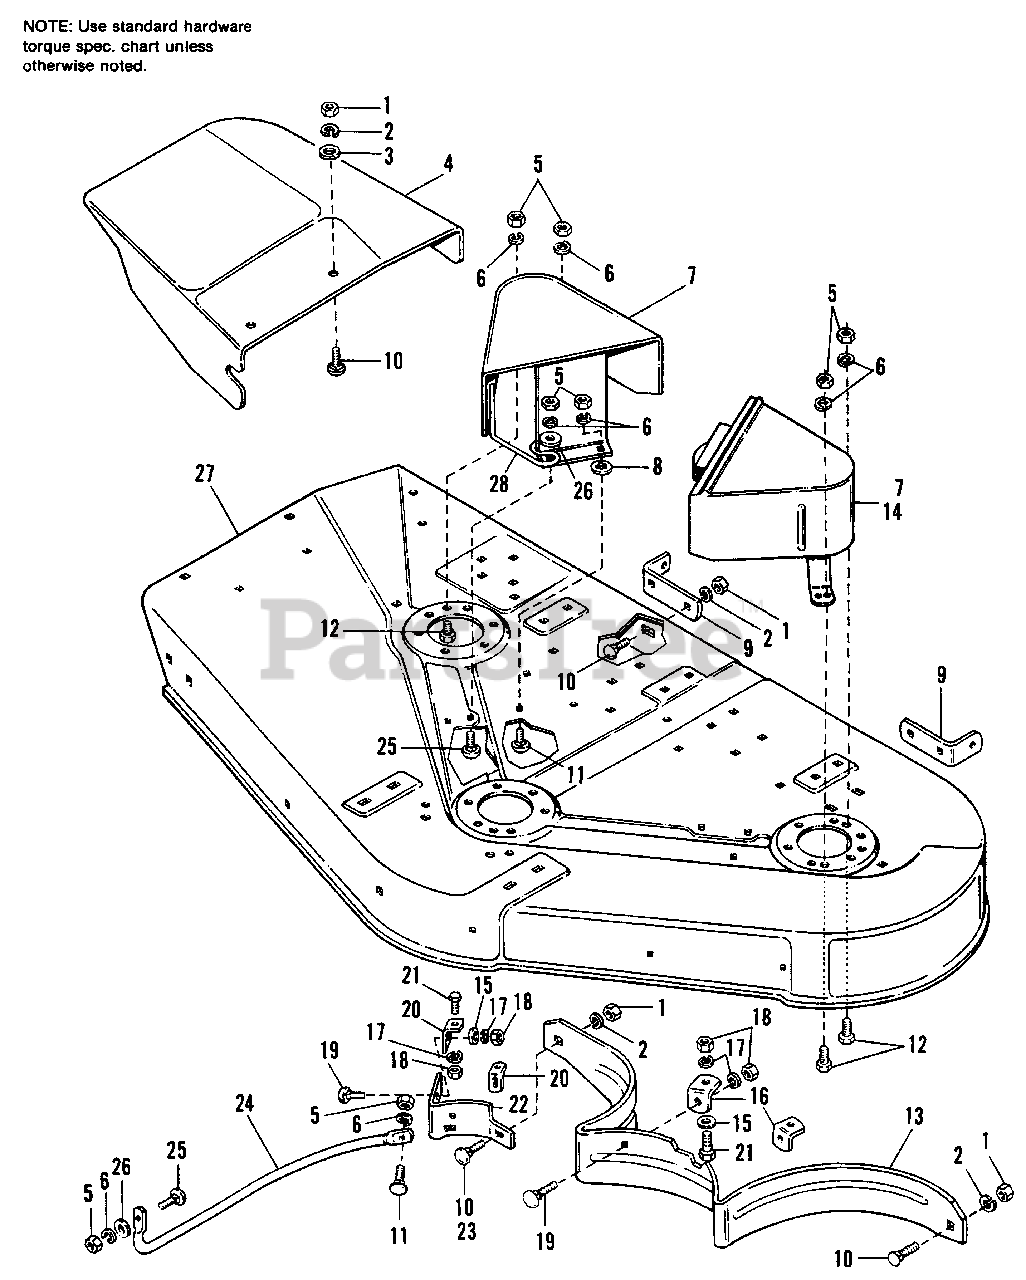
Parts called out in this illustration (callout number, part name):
1	NUT, Hex, 3/8-16 (Qty. 7 used on 48")
2	LOCKWASHER, 3/8 (Qty. 7 used on 48")
3	WASHER, Plain, 3/8
5	NUT, Hex, 5/16-18 (Qty. 8 used on 42")
6	LOCKWASHER, 5/16 (Qty. 8 used on 42")
7	ARBOR COVER ASSY. (Qty. 1 used on 1690708 & Qty. 2 used on 1690709)
7	ARBOR COVER ASSY. (Qty. 1 used on 1691423 & Qty. 2 used on 1691425)
8	PUSHNUT, 5/16 (Qty. 2 used on 42")
9	BRACKET, Roller Support
10	BOLT, Carriage, 3/8-16 x 3/4 (Qty. 6 used on 48")
11	BOLT, Carriage, 5/16-18 x 3/4 (Qty. 2 used on 1690708)
12	CAPSCREW, Hex, 5/16-18 x 1
13	BAFFLE (42")
13	BAFFLE (48")
14	ARBOR COVER ASSY. (1691423 only)
15	WASHER, 1/4
16	CLIP, Baffle
17	LOCKWASHER, 1/4
18	NUT, Hex, 1/4-20
19	BOLT, Carriage, 1/4-20 x 5/8
20	CLIP GUARD & BAFFLE
21	CAPSCREW, Hex, 1/4-20 x 3/4
22	BAFFLE, Discharge
23	BOLT, Carriage, 3/8-16 x 1.00 (48" only)
24	GUARD, Mower Discharge
25	BOLT, Carriage, 5/16-18 x 1
26	WASHER, 11/32 x 1
27	42" ROTARY MOWER HOUSING KIT
27	48" ROTARY MOUWER HOUSING KIT
29	ARBOR COVER ASSY. (1690708 only)
